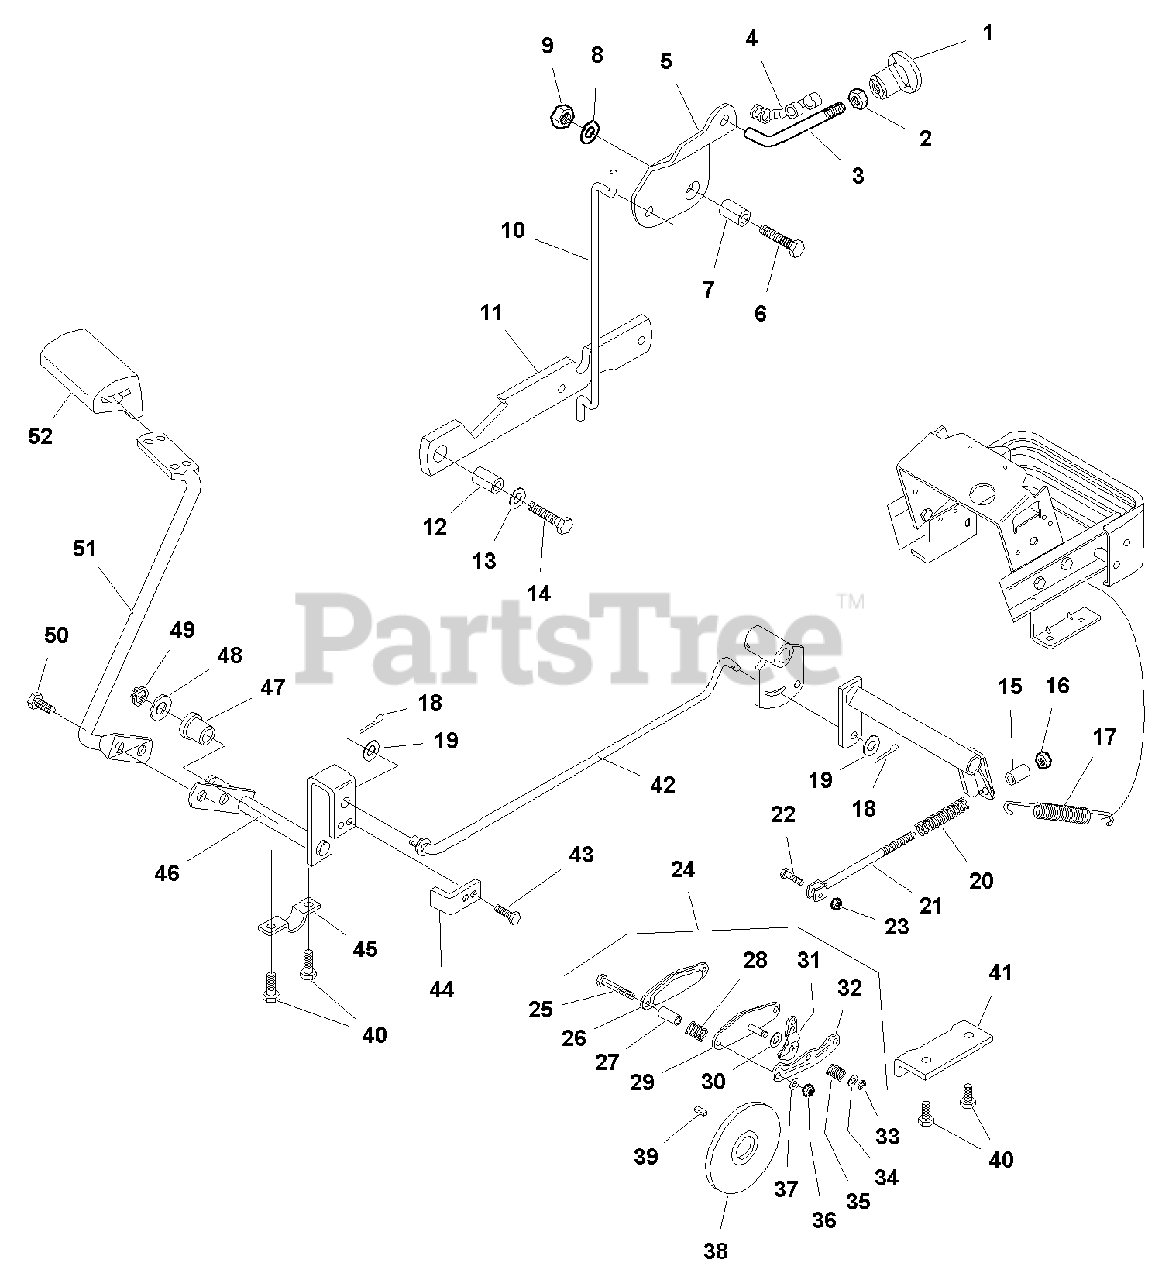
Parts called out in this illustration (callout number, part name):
1	KNOB, Parking Brake
2	NUT, Hex #10-24
3	ROD, Park Brake
5	BRACKET, Park Brake Pivot
6	CARRIAGE BOLT, 1/4-20 x 3/4
7	SPACER, 9/32x 1/2 x 5/16
8	WASHER, 1/4
9	NUT, Hex, Center Lock, 1/4-20
10	ROD, Park Brake
11	BRACKET, Park Brake
12	SPACER, .325 x 3/4 x .63
13	WASHER, 5/16
14	CAPSCREW, Taptite, 5/16-18 x 1-1/4
16	NUT, Hex, Nylon 3/8-16
17	SPRING, Extension
18	PIN, Cotter, 1/8 x 3/4
19	WASHER, Plain, 3/8
20	SPRING, Compression
21	ROD ASSEMBLY, Brake
22	CAPSCREW, Hex, 1/4-20 x 1
23	NUT, Hex, Nylon, 1/4-20
24	CALIPER ASSEMBLY, Brake (Includes Ref. Nos. 25 - 37)
25	CAPSCREW, Hex Head, 1/4-20 x 2
26	PAD, Brake, Outer
28	SPRING, Compression
29	PAD, Brake, Inner
32	BRACKET, Mounting
35	SPRING, Compression
36	NUT, Hex, 1/4-20
37	LOCKWASHER, 1/4
38	BRAKE, Disc
39	KEY, Woodruff, 3/16 x 3/4 #9
40	CAPSCREW, Hex Head, Taptite, 5/16-18 x 3/4
41	BRACKET, Caliper Mtg.
43	RIVET, Pop, 3/16 x 7/16 lg
44	ACTUATOR, Switch
46	BRAKE ARM ASSEMBLY
48	WASHER, 3/4
49	KLIP RING, 3/4
50	CASPCREW, Taptite, 3/8-16 x 1
51	LEVER, Brake
52	PAD, Brake Pedal
